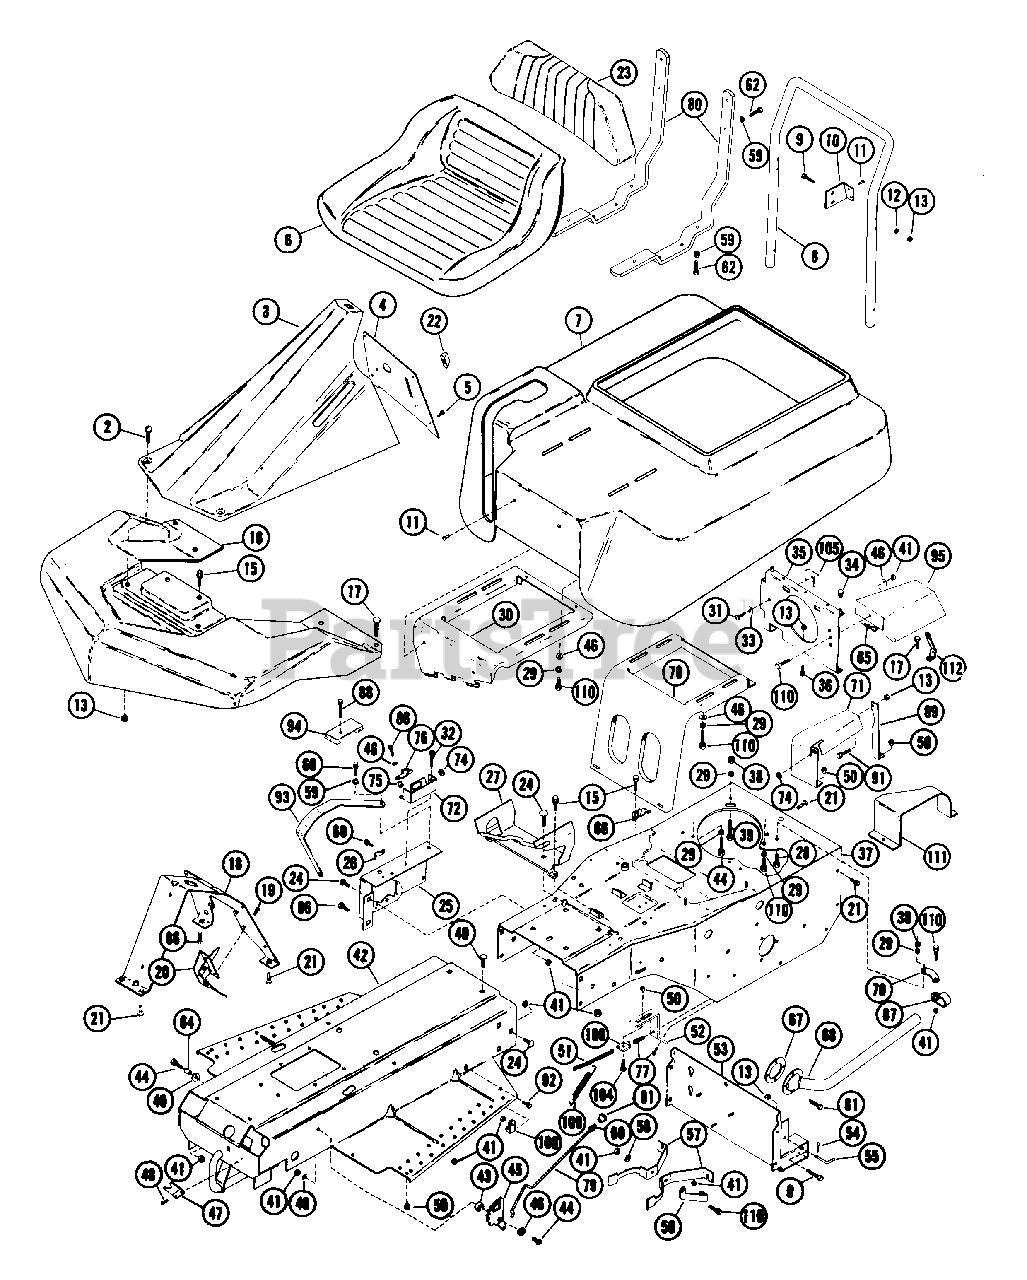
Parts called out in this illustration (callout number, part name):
1	EMPEROR NAME PLATE
2	SCR-MCH .25-20X.63 CRPH PL
4	CONTROL PANEL ASSEMBLY
5	SCR-TAP 10-12X.50 CRPH PL A
6	SEAT
7	ENGINE COVER ASSEMBLY
8	SERVICE BAR
9	BLT-HEX .25-20X1.50 PL GR5
10	BRACKET
11	RVT-POP .187X.402 DOME ST
12	WSHR-FL-STL.312X.734X.065PL
13	NUT-LK-CTR .250-20 PL
15	BLT-SERHFWH .25-20X.50 PL
16	FRONT WHEEL COVERS
17	SCR-SLTR-SERNK .25-20X.62 PL
18	CONTROL PANEL
19	SCR-TAP 10-24X.375 CRPH 1A
20	THROTTLE CONTROL
21	BLT-SERHFWH .31-18X.50 PL
23	SEAT BACK
24	BLT-RDHDSQSHNK .31-18X.50 YZ
25	SHIFT QUADRANT
26	CLIP
27	SEAT HINGE
28	BLT-HEX .31-18X1.50 PL GR2
29	WSHR-LK .312X.097 PL HVY
30	BRACKET
31	SCR-TAP 10-16X1.0 SLHP PL AB
32	SCR-TAP 10-24X.375 CRPH 1A
33	WSHR-FL-STL .250X.562X.049 PL
34	BUMPER GROMMET
35	SEAT LEG
36	BLT-HEX .25-20X.50 PL GR2
37	FRAME
38	NUT-HEX .312-18
39	BLT-HEX .31-18X1.25 PL GR2
40	BLT-RDHDSQNK .312-18X.62 PL
41	NUT-LK .312-18 GR A PL
42	FRONT FRAME ASSY.
43	SPACER -SHLD .344X.500X.469
44	BLT-HEX .31-18X1.00 PL GR 2
45	BRAKE LATCH
46	WSHR-FL-STL .38X.875X.083 PL
47	LOCK SPRING
48	SCR-TAP 10-12X.50 CRPH PL A
49	WSHR-FL-STL .323X.625X.062 PL
50	NUT-LK-FLG .250-20 PL
51	BRAKE CHAIN
52	BRACKET
54	PIN-HAIR INT .09X1.88 PL
55	PIN
56	WSHR-FL-STL .323X.625X.062 PL
57	BELT FINGER
58	BELT FINGER BRACE
59	WSHR-LK .250X.077 HVY PL
60	NUT-LK TOP 10-24 PL
61	SCR-TAP 8-32X.38 SL HWH PL 23
62	BLT-HEX .25-20X.75 PL GR2
64	SPACER .344X1.000X.375
65	MOWER HEIGHT DECAL
66	CLAMP
67	GASKET
68	PIPE
68	EXHAUST PIPE
70	MUFFLER BRACKET
71	SHIELD
72	SWITCH HOUSING
74	GROMMET, .31 ID
75	BSHG, FLG .325X.499X.26X.88
76	CAM NO SCRAP
77	BLT-SERHFWH .25-20X.50 PL
78	SEAT BRACKET
79	PARKING BRAKE ROD
80	SEAT BRACE
86	BLT-SERHFWH .31-18X.75 PL
87	CLIP
88	SCR-TAP 12-14X1.25 CROVH PL 1A
89	BRACE
91	BLT-HEX .25-20X.38 PL GR2
92	BLT-HEX .31-18X.50 PL GR2
93	SHIFT PANEL
95	BAFFLE
104	BLT-RDHDSQNK .25-20X.62 PL
105	CLAMP
106	BRACKET
109	SG-TENS .041X.35X2.11 WLD 8
110	BLT-HEX .31-18X.75 PL GR2
111	HEAT SHIELD
112	CABLE BRACKET
